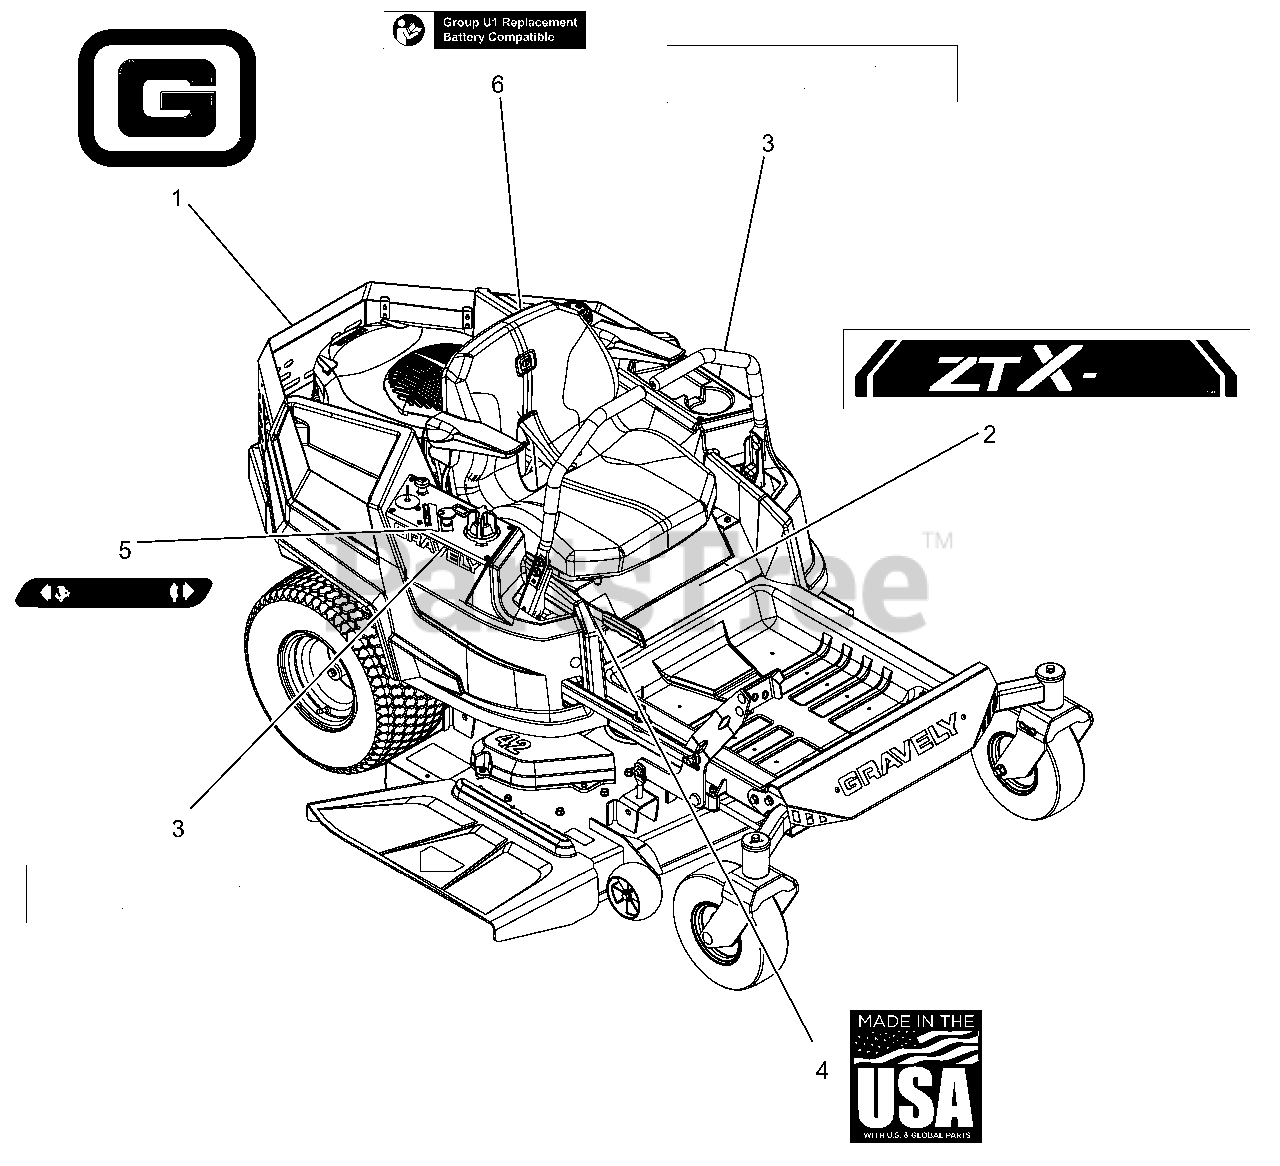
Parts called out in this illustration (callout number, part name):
1	DECAL, GRAVELY BRAND
2	DECAL, GRAVELY ZT X 42
3	DECAL, 9.5" GRAVELY LOGO
4	DECAL, MADE IN USA
5	DECAL, DASH DECAL
6	DECAL, U1 BATTERY REPLACEMENT
